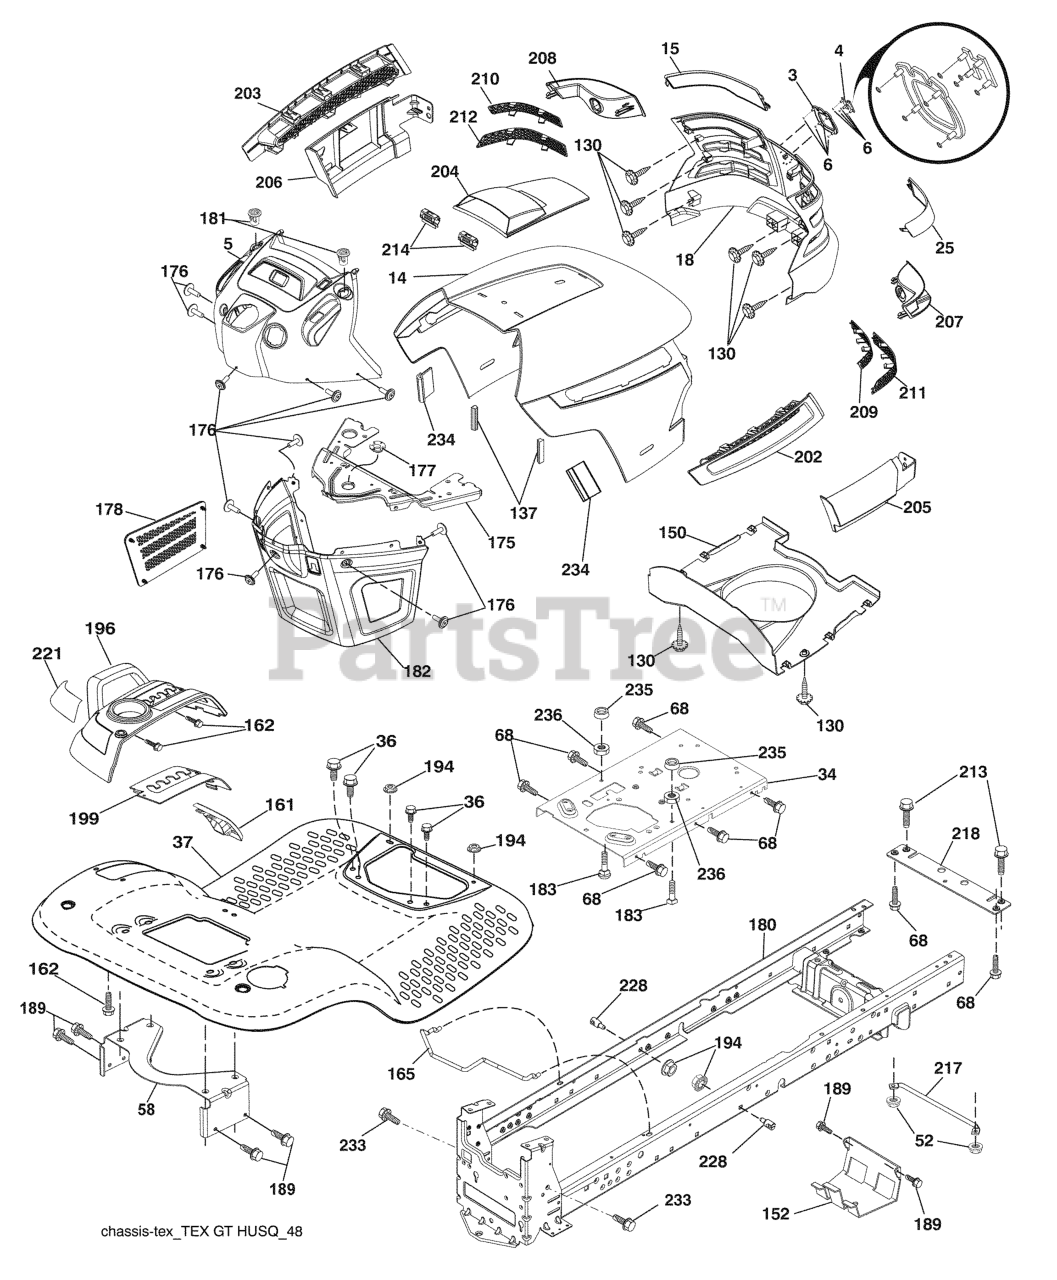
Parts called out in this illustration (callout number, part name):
3	TRIM.HUSQ.TG/CRD.SERVICE
4	RP LOGO
5	DASH.ASM.HUSQ.GT.E.RDGA.W/CK
6	NUT PUSH M
14	HOOD
15	LENS.LH.TEX.GT.HUSQ.CL
18	GRILL.ASM.HUSQ.TG/CRD.W/TRIM
25	LENS.RH.TEX.GT.HUSQ.CL
34	PLATE.ENGINE.WELDED.CHASSIS
36	SCREW 5/16"
37	FENDER.PNT.TX.GT.CH/FW.ORANGE
52	LOCKNUT
58	DRAWBAR.UPPER.2PC,LRG.FENDER
68	Screw Thdrol 5/16-18 x 1/2
130	SCREW.#10 X 0.750.BOS
137	BUMPER DASH
150	AIR.DUCT.HOOD.TEX.GT.HUSQ
152	SHIELD.BROWNING.W/TEX
161	CONSOLE.FUEL.WINDOW.HU
162	SCREW.HI-LO.CONSOLE
165	SUPPORT.TANK.REAR.W/TEX
175	PLATE.CROSSMEMBER.HUSQ
176	SCREW.#10-24X5/8.RN.QU
177	BUSHING, STEERING
178	CARGO.ASM.NET.TXGT.W/C
180	CHASS.WLDMNT.TLT.12GA/2PC.20"
181	BUSHING.MNT.FEND.CRGO.
182	DASH.LOWER.COMMON.12V.ADAPTOR
183	BOLT.5/16-18X1-1/4 FULL.THREAD
189	SCREW
194	NUT LOCK HEX FLANGE 5/16-18
196	CONSOLE.ASM.DCKLFT.W/RF.HQ.DLR
199	PLATE.DECK.LIFT.HUSQVARNA.GT
202	VENT.SIDE.HOOD.HUSQ.RH.GREY
203	VENT.SIDE.HOOD.HUSQ.LH.GRAY
204	HOOD VENT
205	SKIRT.HOOD.SIDE.HUSQ.RH.GREY
206	SKIRT.HOOD.SIDE.HUSQ.LH.GREY
207	BEZEL.RH.TEX.GT.HUSQ
208	BEZEL.LH.TEX.GT.HUSQ
209	INSERT.HEX.GRILL.HUSQ.GREY
210	INSERT.HEX.GRILL.HUSQ.
211	INSERT.HEX.GRILL.HUSQ.
212	INSERT.HEX.GRILL.HUSQ.
213	BOLT
214	CLIP.RETAINER.TINNER.
217	ROD.PIVOT.HOOD
218	X-PIECE.HOOD.STOP.NON/
221	REFLECTOR.LH.TEX GT HU
228	STUD.FASTNER.W/ANTI-ROTATE
233	BOLT.SHOULDER
234	BUMPER.HOOD.TEX.HUSQVARNA
235	SPACER FENDER
236	NUT.CENTERLOCK.5/16-
